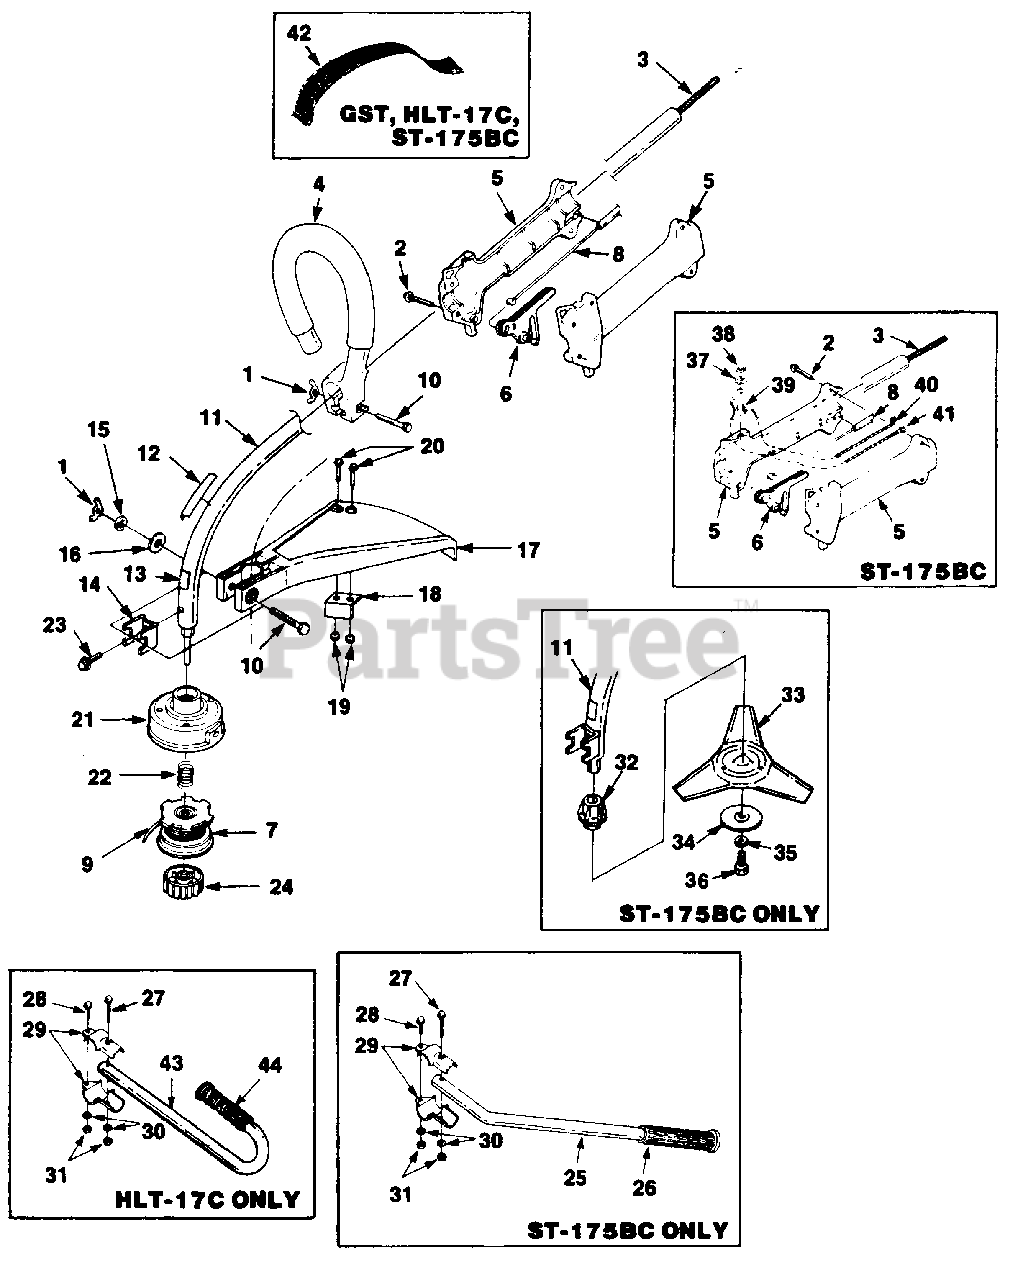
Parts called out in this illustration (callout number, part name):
1	NUT- Wing
2	SCREW- Plastite (#8 x 3/4")
3	SHAFT- Flexible
4	HANDLE- Front (ST-145, ST-155, HGT)
5	HANDLE GRIP ASSEMBLY
6	TRIGGER
7	SPOOL & STRlNG(ST-155)
8	CABLE- Throttle
9	LINE- Replacement (.080 Dia.) (100 Ft.)
10	SCREW (10-24 x 2")
11	HOUSING- Drive Shaft
12	DECAL- Starting Instructions
13	DECAL- Warning
14	CLAMP
15	LOCKWASHER (1/4")
16	WASHER- Flat (1/4")
17	DEFLECTOR- Grass
18	BLADE- Cut off (ST-145. ST-155)
19	NUT- (10-24)
20	SCREW- (10-24 x 7/8")
21	HOUSING & EYELET- Dual line
22	SPRING- Compression
23	SCREW (#10 x 1/2")
24	RETAINER- Spool (R.H. Thread)
25	HANDLE BAR (ST-175BC)
26	GRIP (ST-175BC)
27	SCREW (ST-175BC, HLT-17C)
28	SCREW (ST-175BC, HLT-17C)
29	CLAMP (ST-175BC, HLT-17C)
30	WASHER (ST-175BC, HLT-17C)
31	NUT (ST-175BC, HLT-17C)
32	ADAPTOR (ST-175BC, HLT-17C)
33	BLADE- Weed (ST-175BC, HLT-17C)
34	WASHER- Cupped (ST-175BC, HLT-17C)
35	WASHER (ST-175BC, HLT-17C)
36	SCREW (ST-175BC, HLT-17C)
37	PLATE- Indicating (ST-1 75C, ST-1 75BC, HLT-17C)
38	NUT (ST-175C, ST-175BC, HLT-17C)
39	SWITCH- Toggle (ST-175C, ST-175BC, HLT-17C)
40	LEAD- Electrical (ST-175C, ST-175BC. HLT-17C)
41	A LEAD- Ground (ST-175C, ST-175BC, HLT-17C)
42	HARNESS w/connector (GST, ST-175BC, HLT-17C)
43	HANDLE BAR ("J") (HLT-17C)
44	GRIP (HLT-17C)
